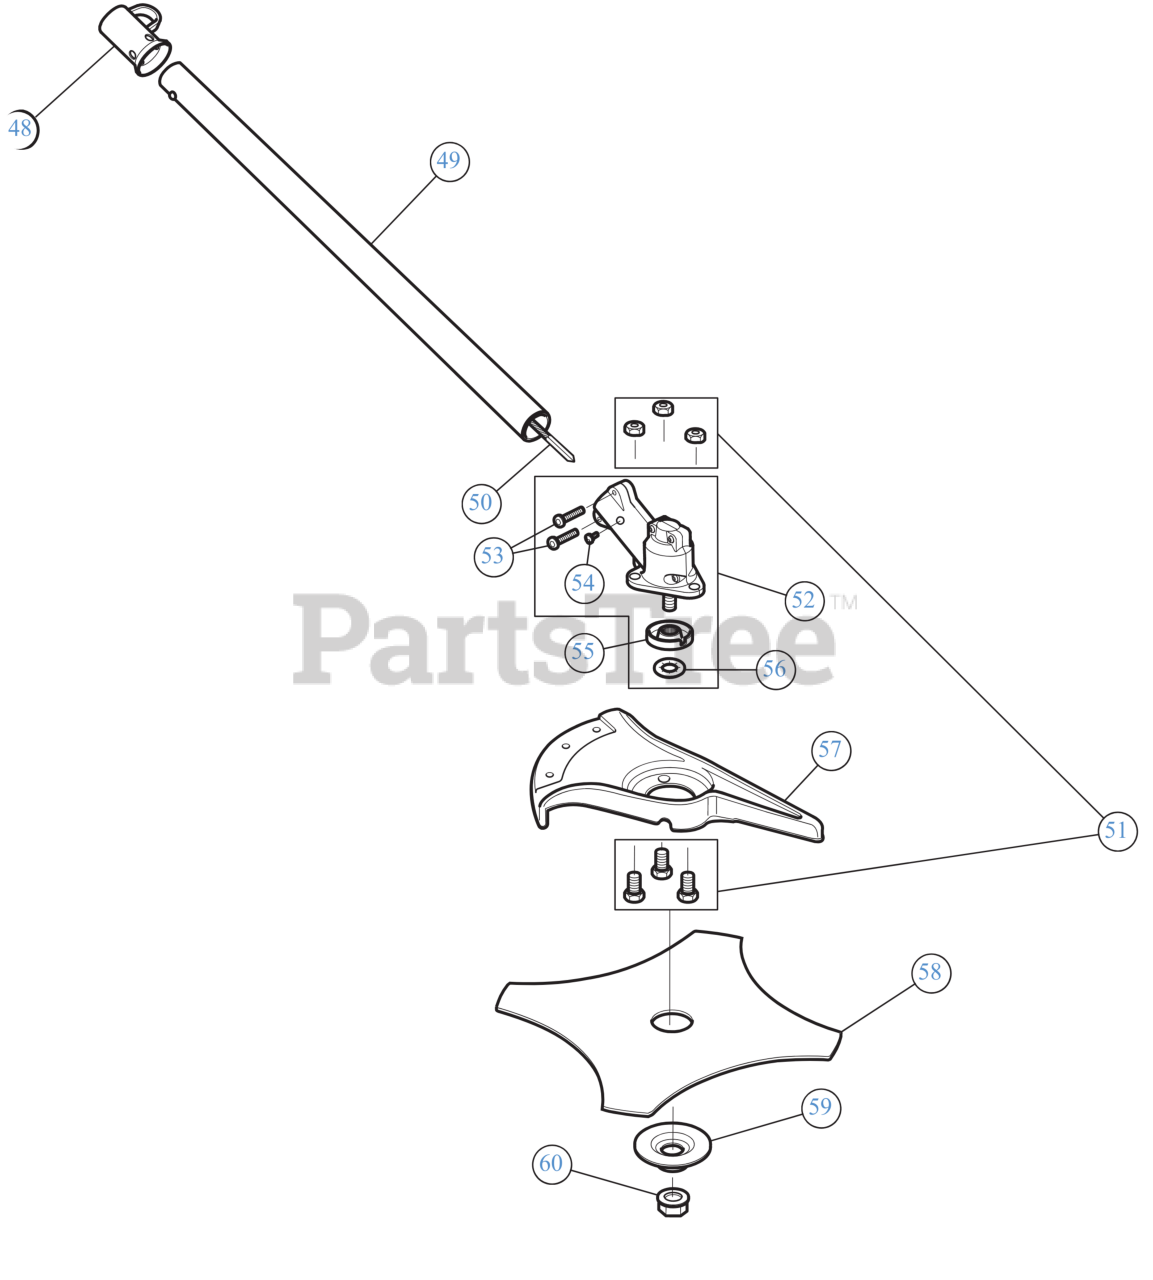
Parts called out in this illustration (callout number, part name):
49	BOOM ASSEMBLY LOWER
50	LOWER DRIVE SHAFT
51	SCREW SET-GUARD MT
52	GEARBOX ASSEMBLY
54	SCREW, 8-32 x .312 P
55	SPACER-GEARBOX
56	PALNUT:3/8" DIAM
57	SHIELD-BLADE CAST
58	BLADE 4-TOOTH
59	WASHER-BLADE CLAMP BRUSH CUT
60	BLADE LOCK NUT
